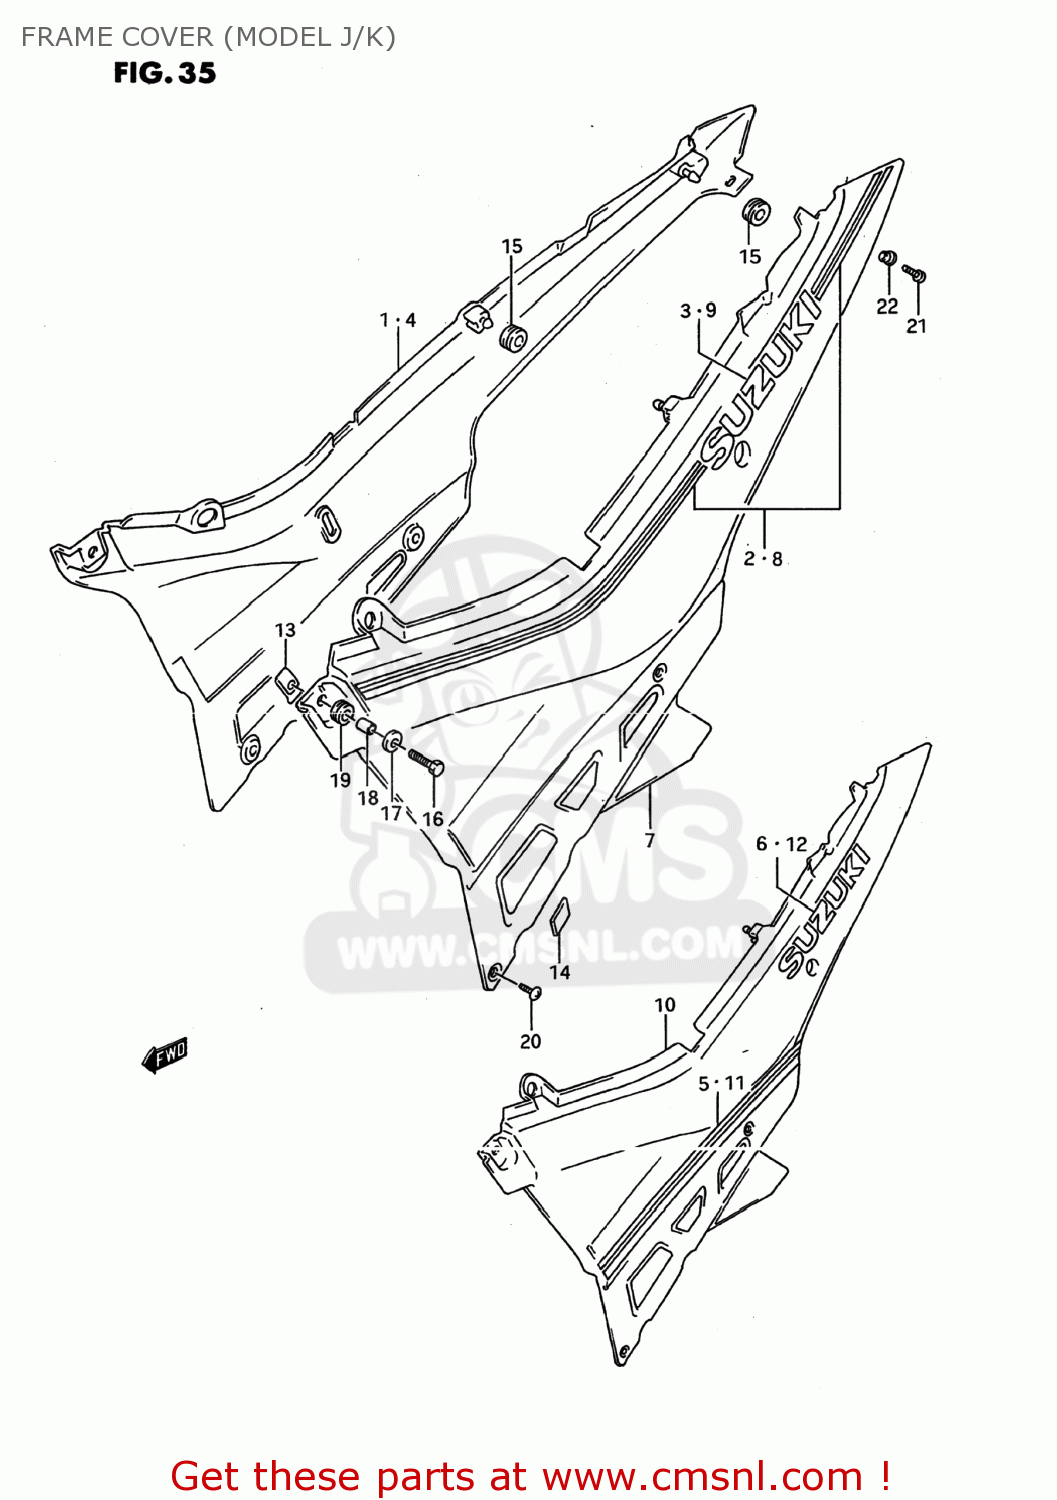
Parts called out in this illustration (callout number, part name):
1	COVER,FRAME,RIGHT
2	TAPE SET,FRAME COVER,RIGHT
3	EMBLEM
4	COVER,FRAME,RIGHT
5	TAPE,FRAME COVER RH
6	EMBLEM
7	COVER,FRAME,LEFT
9	EMBLEM
10	COVER,FRAME,LEFT
11	TAPE,FRAME COVER LH
12	EMBLEM
13	PLATE,FRAME COVER
14	CUSHION,FRAME COVER
15	CUSHION
16	BOLT(6X20)
17	WASHER
18	SPACER (6.1X9X9)
19	CUSHION
20	SCREW(5X15.3)
21	SCREW, FRONT & REAR
22	WASHER
